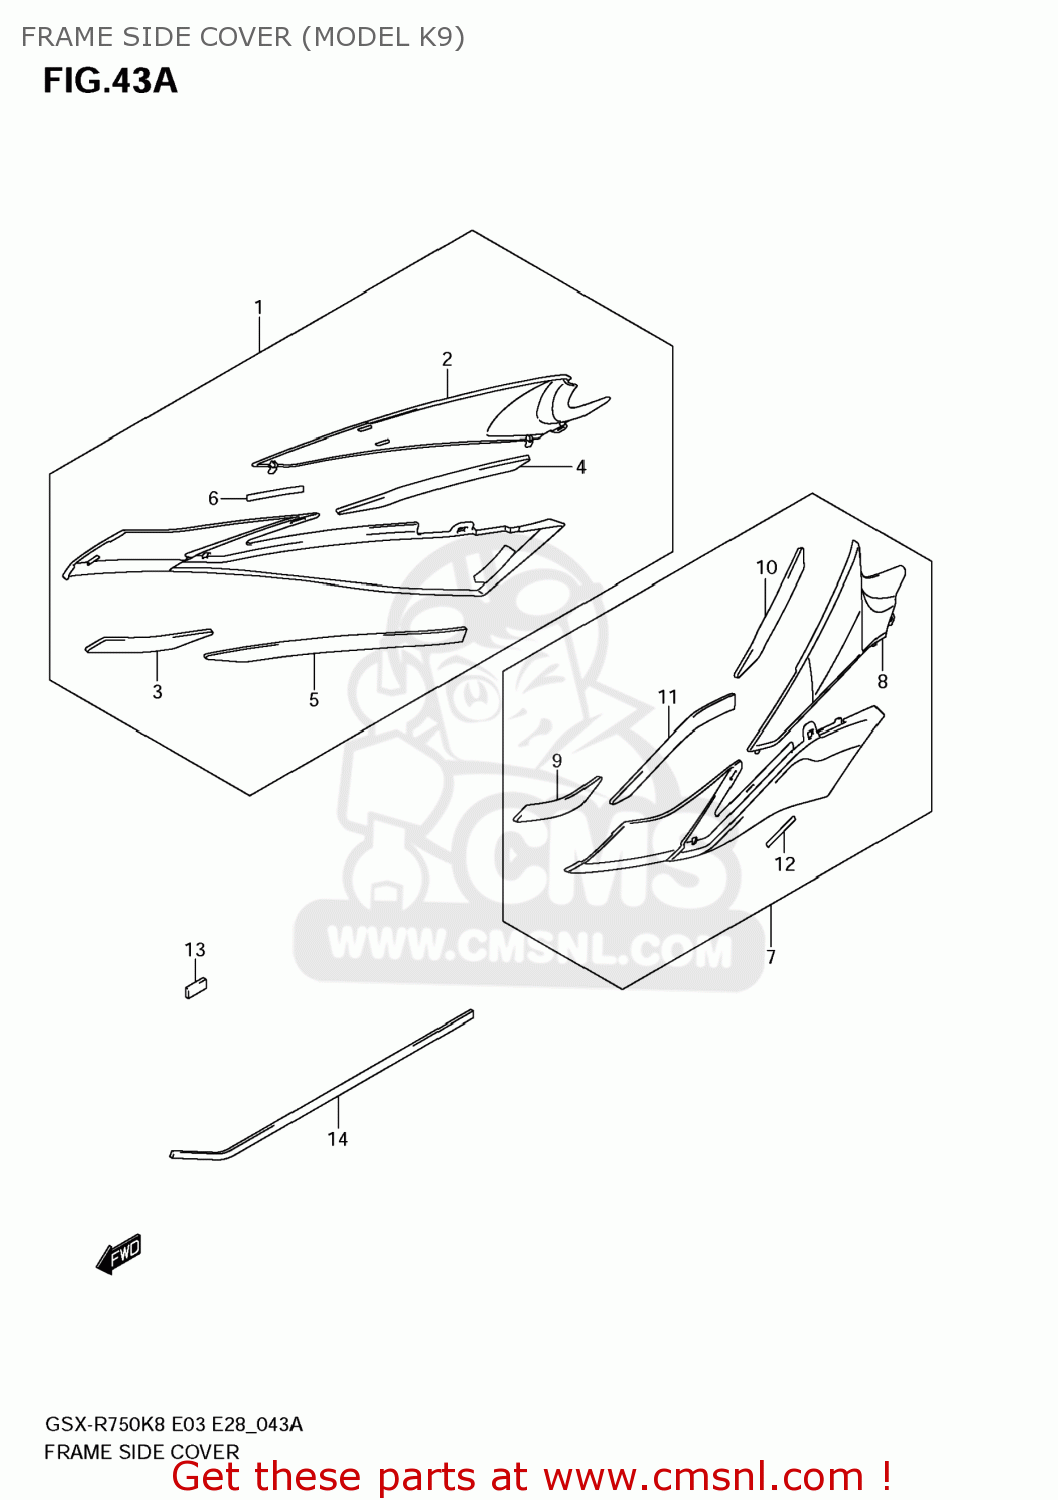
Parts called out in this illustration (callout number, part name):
1	COVER,FRAME SIDE,R(BLACK)
2	COVER,UPR,R
3	CUSHION,FRAME COVER FR,R
4	CUSHION,FRAME COVER UPR,R
5	CUSHION,FRAME COVER LWR,R
6	CUSHION,CTR
7	COVER,FRAME SIDE,L(BLACK)
8	COVER,UPR,L
9	CUSHION,FRAME COVER FR,L
10	CUSHION,FRAME COVER UPR,L
11	CUSHION,FRAME COVER LWR,L
12	CUSHION,CTR
13	CUSHION
14	CUSHION,SIDE COVER UPR
